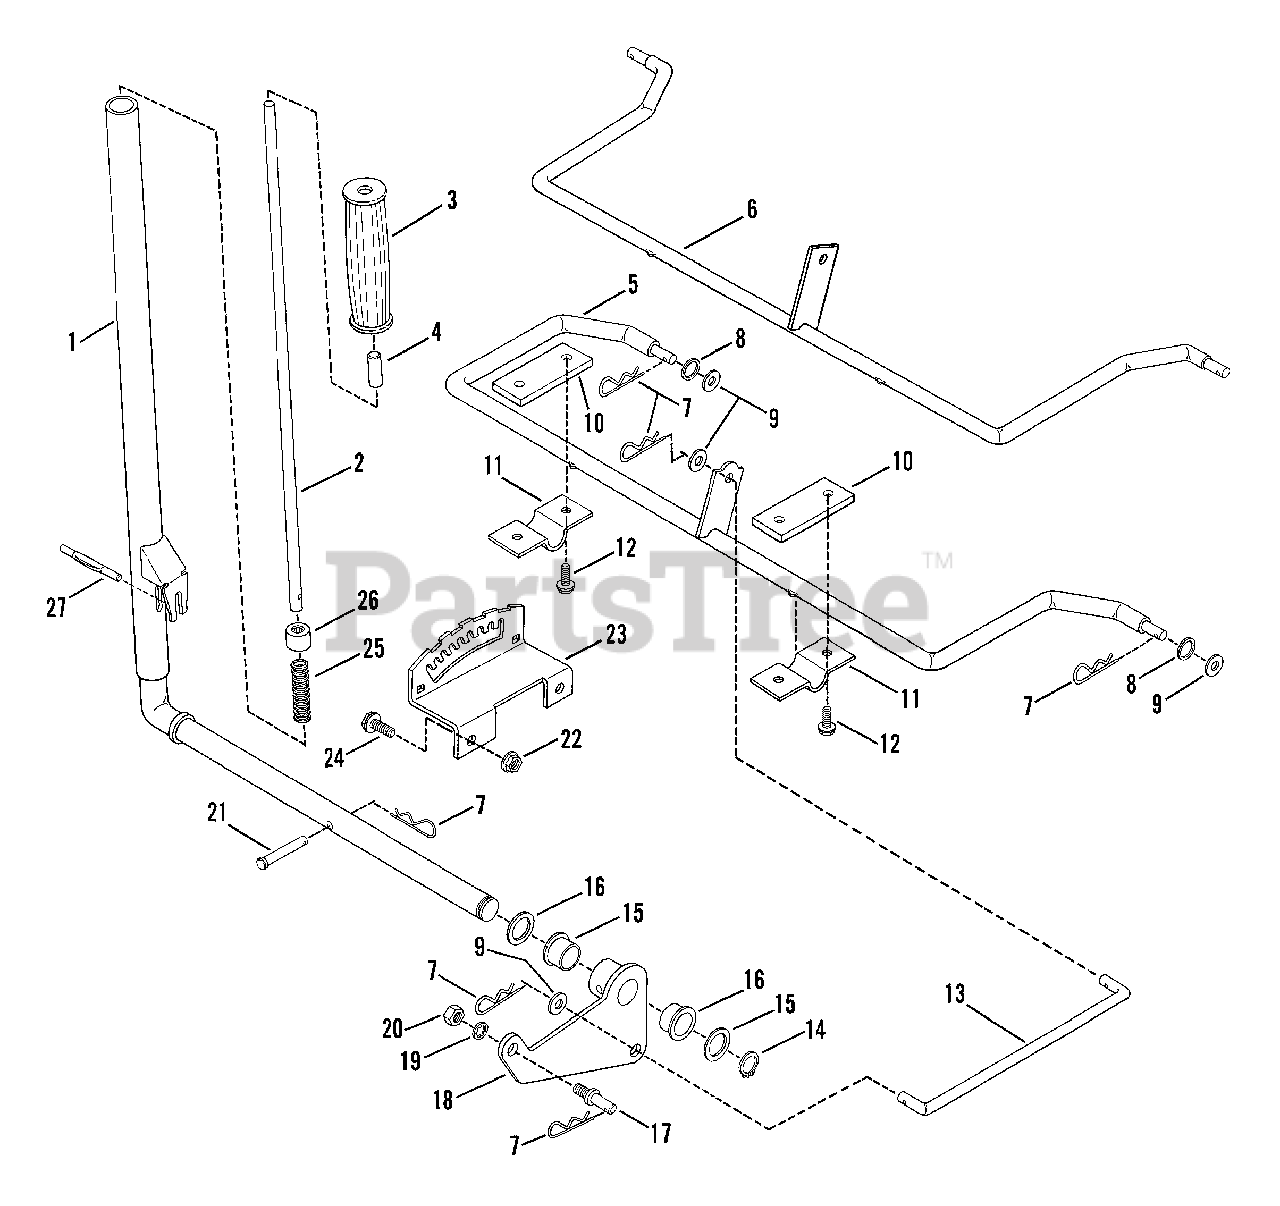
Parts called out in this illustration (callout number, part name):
1	ARM, Implement Lift Lever
2	ROD, Lift Lever
3	GRIP, Lift Lever
4	CAP, Lift Release
5	ARM, Rear Lift (41" Deck Only)
6	ARM, Rear Lift (33" Deck Only)
7	PIN, Hair, 3/32x1-1/2"
8	WASHER, Shim
9	WASHER, 3/8 SAE Flat
10	SPACER (33" Deck Only)
11	BRACKET, Arm
12	SCREW, 5/16-18x5/8"
13	LIFT-ROD
14	RING, Retaining
15	WASHER, Lift Lever
16	BEARING, Lift Lever
17	STUD
18	PIVOT ASSM'Y.,Lift Lever
19	WASHER, 3/8 Int. Tooth Lock
20	NUT, 3/8-24 Hex
21	PIN, Clevis, 5/16x1-11/16"
22	LOCKNUT, 3/8-16 Hex Flange
23	QUADRANT, Lift Lever
24	BOLT, 3/8-16 Hex Flange Lock
25	SPRING, Lift Lever
26	PLUG, Lift Lever
27	GROOVE-PIN, 1/4x2-1/4"
